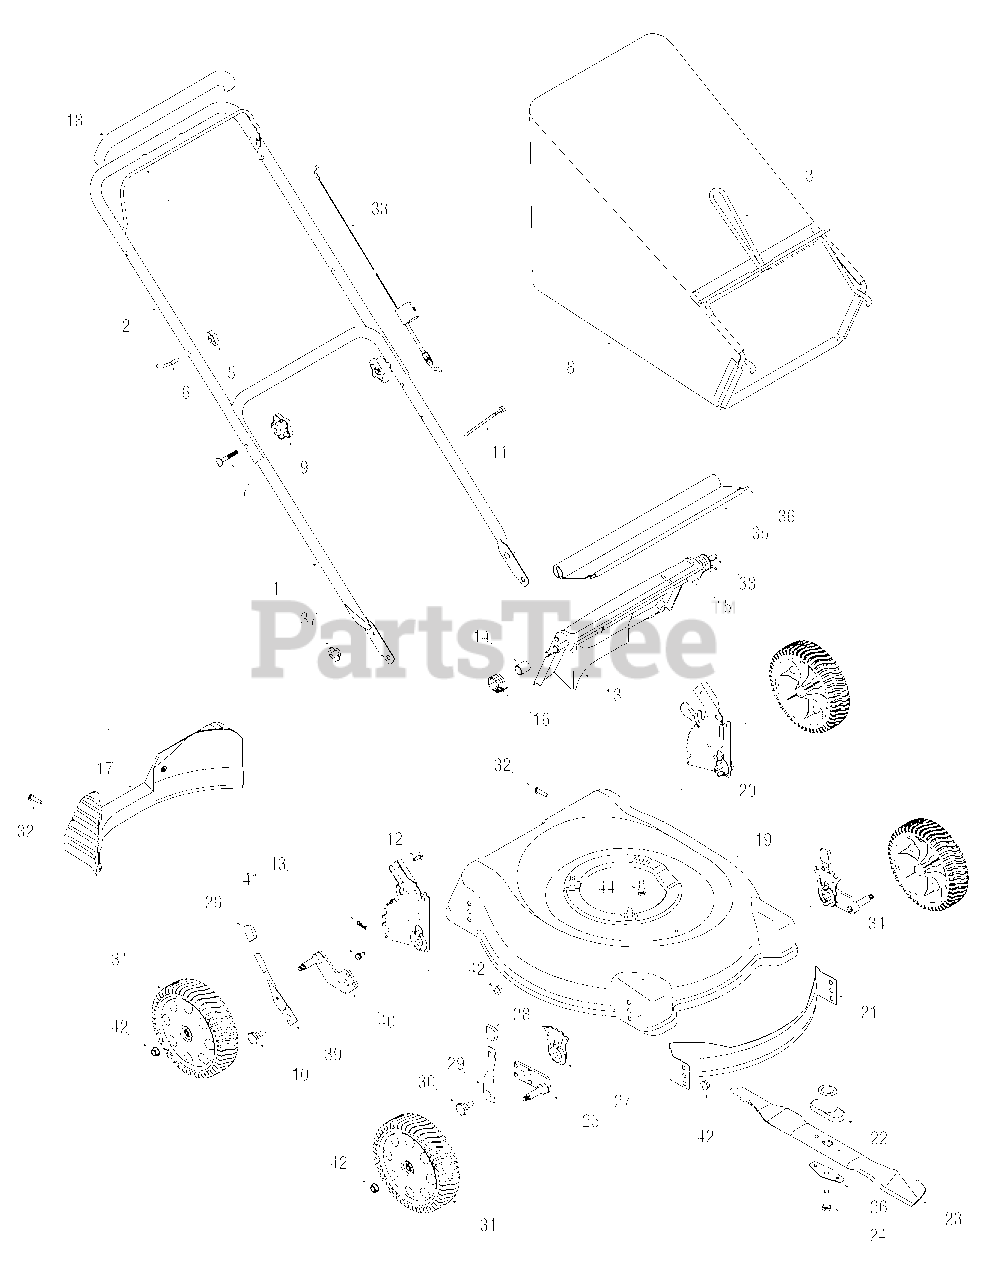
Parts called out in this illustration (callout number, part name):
6	Rope Guide
7	Carriage Bolt, 5/16-18 x 2
8	Grass Bag Assembly
9	Hand Knob
10	Shoulder Screw
11	Cable Tie
12	Carriage Bolt ,1/4-20
13	Rear Discharge Door
14	Spacer
15	Torsion Spring - LH
16	Torsion Spring - RH
17	Rear Baffle
18	Bail Cover
20	Rear Handle Bracket Assy. LH
20	Rear Handle Bracket Assy. RH
21	Front Baffle
22	Blade Adapter
23	Mulching Blade
24	Hex Bolt , 3/8-24 x 1.5
25	Pivot Arm Assembly RH (8" wheel)
25	Pivot Arm Assembly LH (8" wheel)
26	Blade Bell Support
27	Front Adjustment Plate
28	Adjustment Lever Knob
29	Spring Lever Assembly
30	Shoulder Screw
31	Front Wheel, 8 x 2.125
32	Screw, 1/4-15 x 1.250
33	Control Cable - 40"
34	Height Adjustment Assembly RH
34	Height Adjustment Assembly LH
35	Trailshield
36	Trailshield Wire
37	Wing Nut, 1/4-20
38	Rear Door Pivot Rod
39	Spring Lever
40	Pivot Arm Assembly - RH
40	Pivot Arm Assembly - LH
42	Flange Lock Nut, 3/8-16
43	Hairpin Clip
44	TT Sems Screw, 3/8-16 x 1.0
